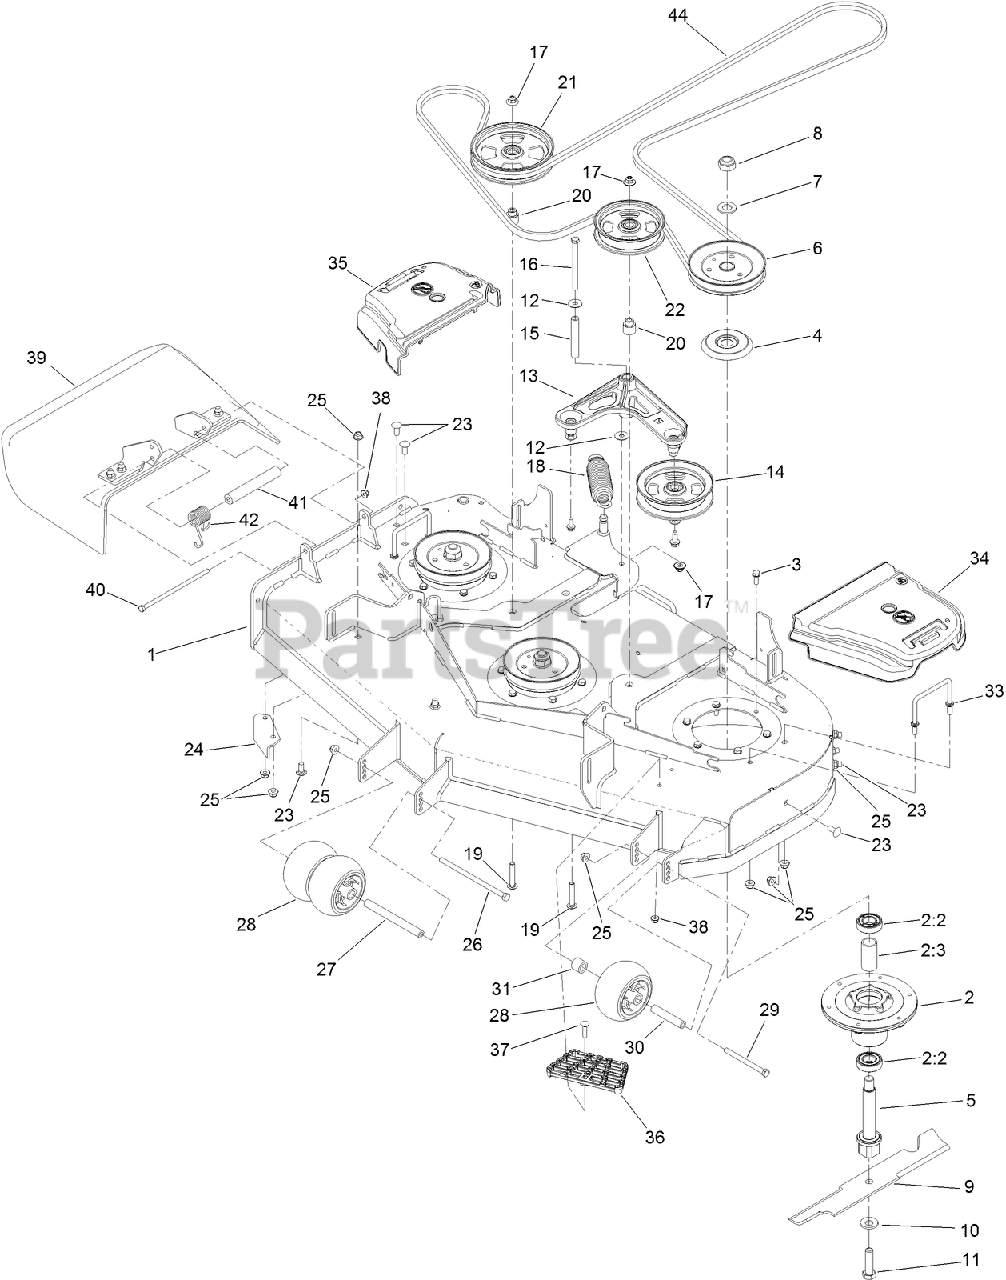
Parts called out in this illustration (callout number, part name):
1	DECK DECAL ASSEMBLY
2	SPINDLE ASM
2:2	BEARING-BALL
2:3	SPACER-BEARING
3	SCREW-TAPTITE
4	SHIELD-BEARING
5	SHAFT-SPINDLE
6	PULLEY-B SECTION
7	WASHER
8	NUT-LOCK, NI
9	BLADE-ROTARY, 16.5IN (HI FLOW)
10	WASHER-BELLEVILLE
11	SCREW-BLADE
12	WASHER
13	IDLER ARM ASM
14	PULLEY-IDLER, FLAT
15	BUSHING
16	SCREW-HH
17	NUT-FLANGE, NI
18	SPRING-EXTENSION
19	BOLT-CARR, SHORT NECK
20	BUSHING-IDLER
21	PULLEY-IDLER, FLAT
22	PULLEY-IDLER,FLAT
23	SCREW-CARR
24	BAFFLE-DISCHARGE
25	NUT-HF, NI
26	SCREW-HH
27	SPACER-WHEEL
28	ROLLER-SCALP, ANTI
29	SCREW-HH
30	TUBE-SPANNER
31	TUBE-SPACER
33	WIREFORM-COVER
34	COVER-BELT, LH
35	COVER-BELT, RH
36	STEP-DECK
37	SCREW-CARR
38	NUT-HF, NI
39	RUBBER DEFLECTOR ASM
40	SCREW-HH
41	SPACER
42	SPRING-TORSION
44	BELT-V
